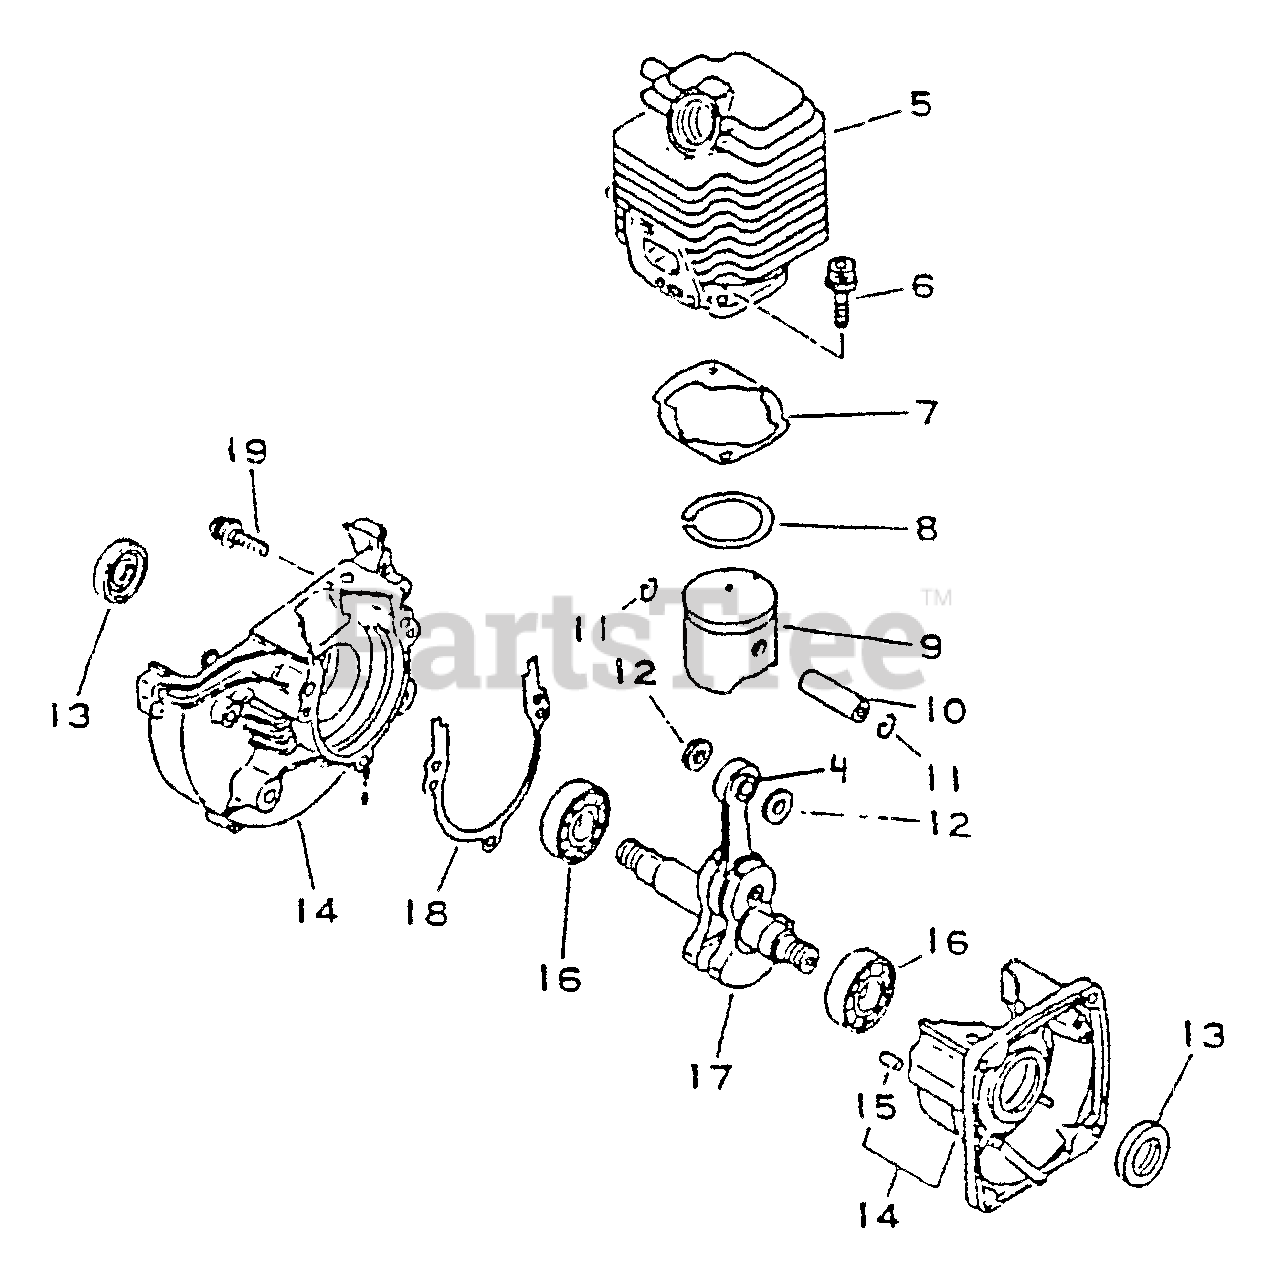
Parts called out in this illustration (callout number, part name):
4	BEARING, NEEDLE
5	CYLINDER
6	SCREW - 5X22
7	GASKET, CYLINDER
8	RING, PISTON
9	PISTON
10	PIN, PISTON
11	RING, RETAINING
12	SPACER, PISTON
13	SEAL, OIL
14	CRANKCASE KIT
15	PIN - LOCATING
16	BEARING, BALL - 6201
17	CRANKSHAFT ASSY
18	GASKET, CRANKCASE
19	SCREW - 5X28
